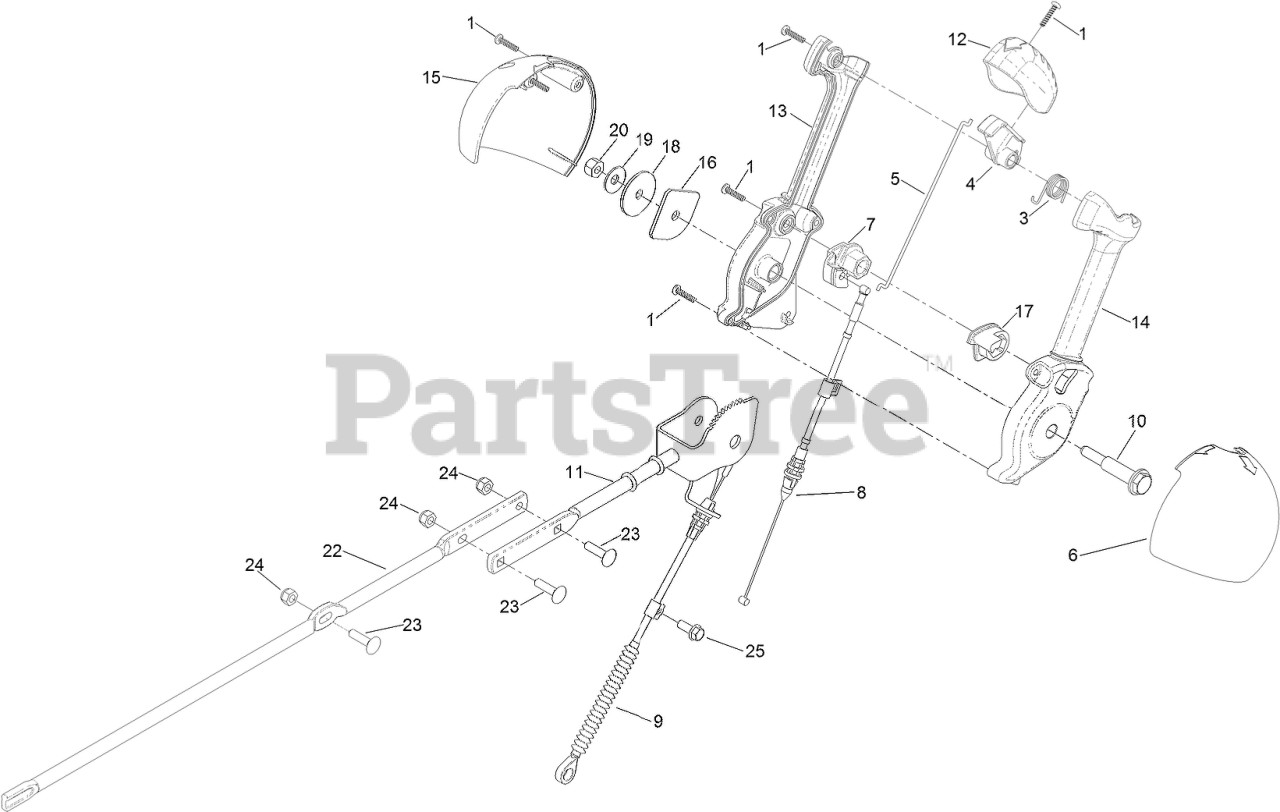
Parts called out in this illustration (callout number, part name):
1	SCREW-PPH
3	SPRING-TORSION
4	TRIGGER-LATCH
5	LINK-LATCH
6	COVER-LEVER, CHUTE (LH)
7	LEVER-CABLE, DEFLECTOR
8	CABLE-RELEASE, CHUTE
9	CABLE-CONTROL, DEFLECTOR
10	SCREW-SHOULDER
11	ROD-CONTROL, CHUTE
12	CAP-LEVER
13	LEVER-CONTROL, CHUTE (RH)
14	LEVER-CONTROL, CHUTE (LH)
15	COVER-LEVER, CHUTE (RH)
16	PLATE-FRICTION
17	PAWL-LATCH
18	WASHER-NYLON
19	WASHER-BELLEVILLE
20	NUT-LOCK, NI
22	ROD-CHUTE
23	SCREW-CARR
24	NUT-LOCK, NI
25	SCREW-HWH
